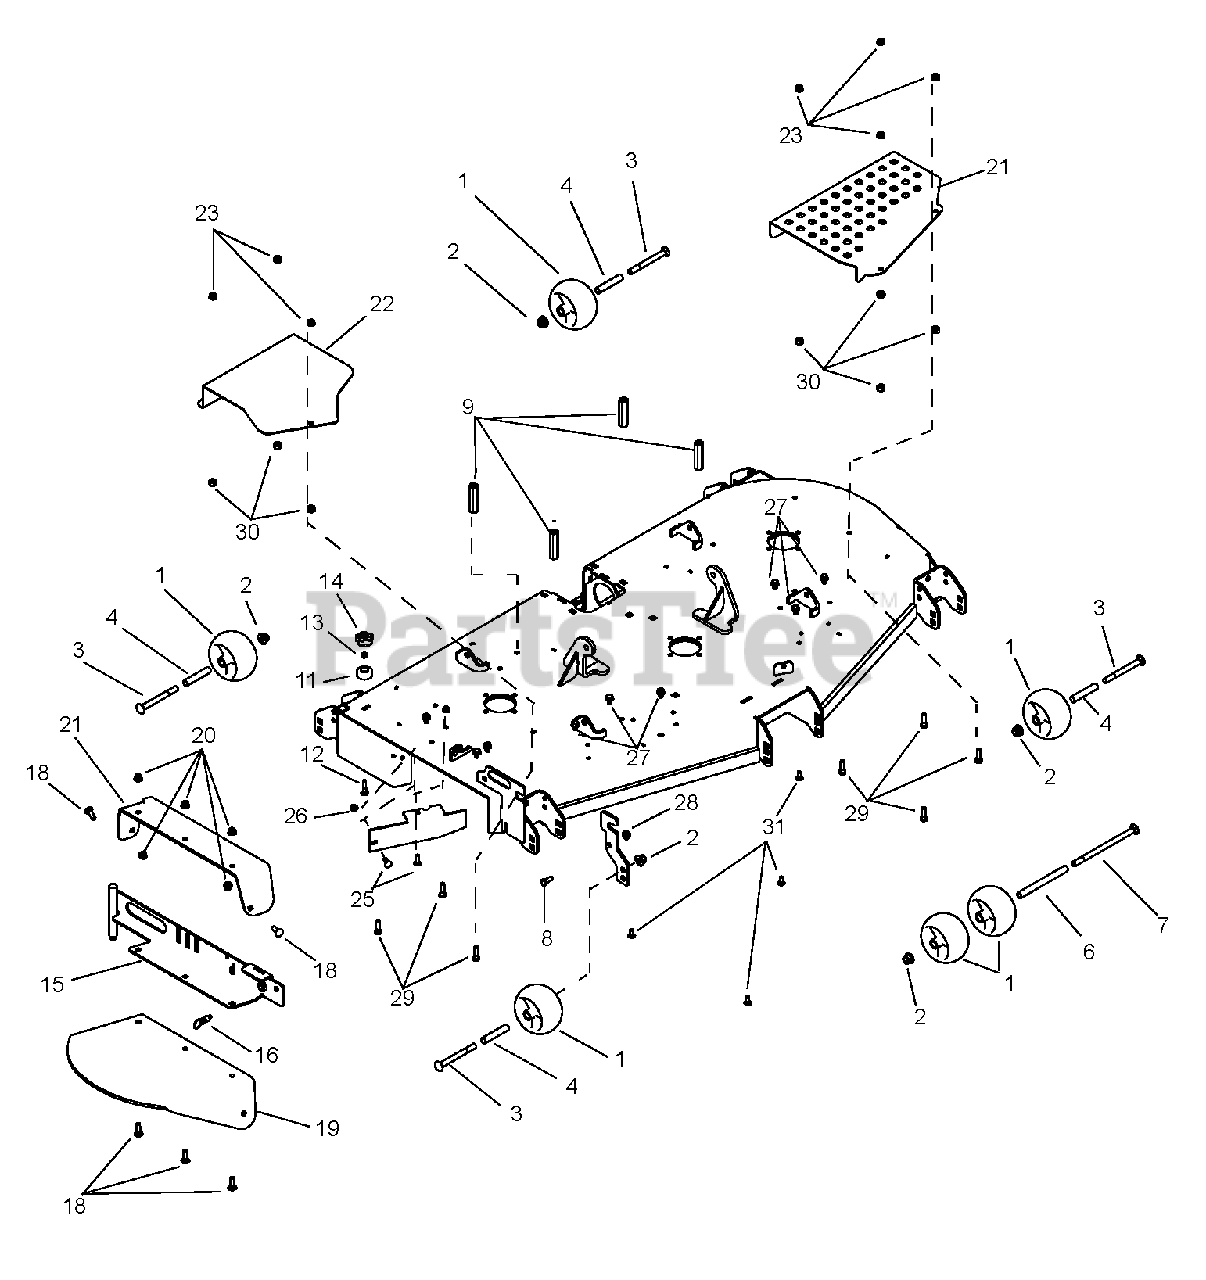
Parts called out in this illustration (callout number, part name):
1	Wheel, Antiscalp
2	Nut .50-13 Nyloc Flange
3	Bolt-Round Head Square Neck .50-13 x 5.00 YZ
4	Spacer, .510 x .625 x 3.35
5	Chute Storage Bracket- Red
6	Spacer, .510 x .625 x 6.70
7	Bolt, Round Head Square Neck .50-13 x 8.50
8	Bolt, Hex .38-16 x 1.00
9	Nut-Coupling .31-18 x 3.00
10	60" Discharge Baffle-Red
11	Bumper, Recessed 1.50 x .63
12	Bolt, Round Head Square Neck .31-18 x 1.50
13	Nut, Locking-Center .31-18
14	Knob, Clamping .312-18 Nyloc
15	52"-60" Discharge Chute Mounting Weldment-Red
16	Pull Pin, .50-13 Thread x .310 Diameter Plunger
17	Rubber Discharge Chute Support-Red
18	Bolt, Round Head Square Neck .38-16 x 1.25
19	Chute, Rubber Discharge
20	Nut, .38-16 Nyloc Flange
21	Guard, 60" Left Hand Spindle
22	Guard, 60" Right Hand Spindle
23	Bolt, SEMS .31-18 x .62
24	Washer, Internal Lock .375
25	Bolt, Round Head Square Neck .31-18 x 1.00
26	Nut, Nyloc Flange .31-18
27	Screw, Tapping .38-16 x .50
28	Nut, Center Lock .38-16
29	Bolt, Hex .38-16 x 1.25
30	Nut, Heavy Hex .38-16
31	Bolt, Roundhead, Squareneck .31-18 x .75
